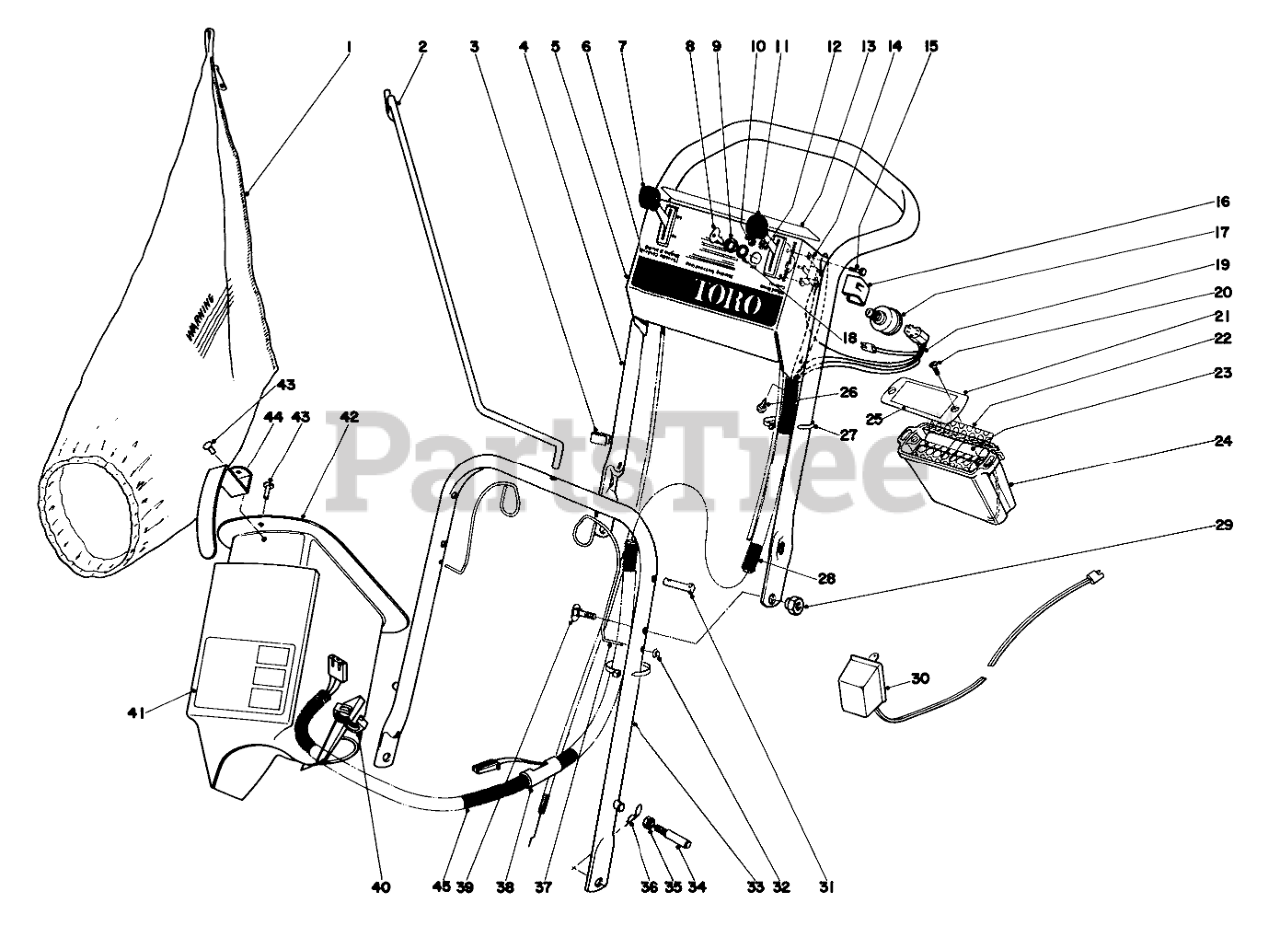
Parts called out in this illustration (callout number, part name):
1	BAG REPLACMNT44-0540
2	Bag Rod
3	BOWDEN CLIP
4	UPPER HANDLE
5	Control Plate
6	Decal Control Plate
7	Control Throttle
8	Key
9	NUT-HH
10	NUT-HEX
11	Traction Control
12	WASHER-FLAT
13	Decal Safety Instructions
14	CONTROL SWITCH
15	SCREW-HH
16	Cover Switch
17	SWITCH-STARTER
18	WASHER-TOOTH, INTERNAL
19	Wire Harness
21	Cover
22	Spacer
23	Battery Pack
24	Container Pack
25	Decal
26	SCREW-HWHTF
27	TIE-CABLE
28	Cover Wiring Harnes Upper
29	Pivot Nut
30	Charger
31	Latch Pin
33	Lower Handle
34	HANDLE PIN
35	Nut
36	PIN-COTTER, HAIR
37	Spring Latch
38	Breakout Fitting
39	HANDLE SCREW
40	RING FITTING
41	Decal Instructions
42	Grass Chute (Incl. Ref. #41, 43, 44)
43	RIVET 3/16 X 7/16
44	HANDLE-GRASS CHUTE
45	Cover Wiring Harness Lower
